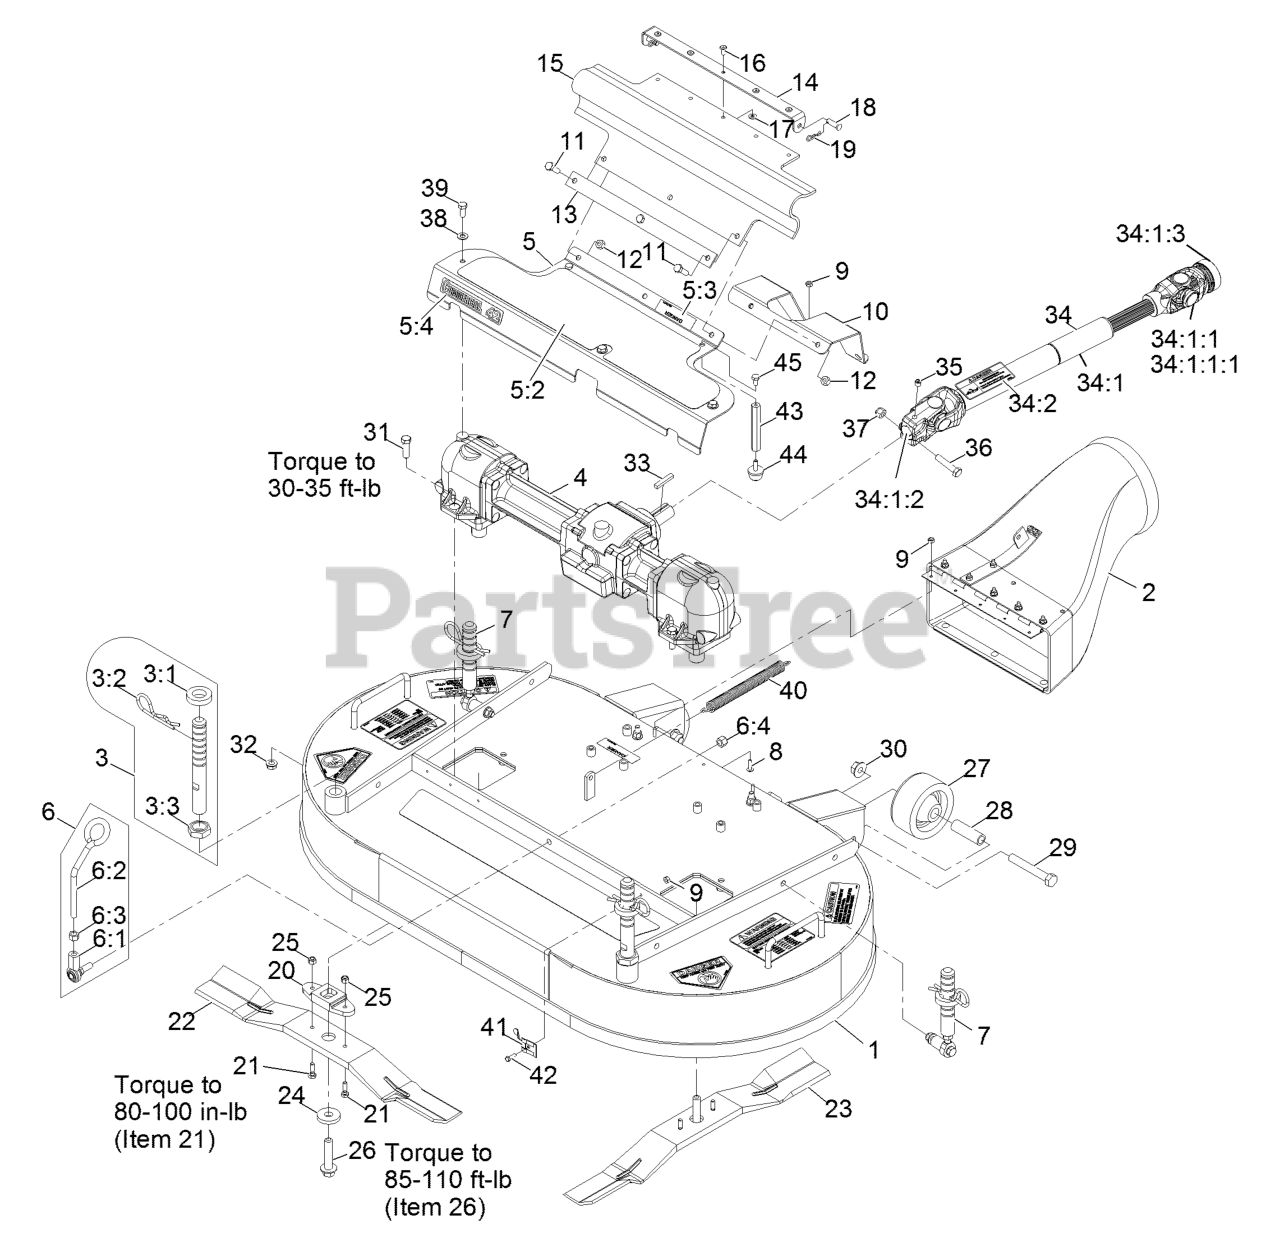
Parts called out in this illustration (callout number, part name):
1	DECK ASM
2	DISCHARGE TUBE ASM
3	FRONT DECK HEIGHT ADJUST
3:1	SPACER-DECK SUPPORT
3:2	PIN-CUT HEIGHT
3:3	NUT-JAM
4	GEARBOX ASM
5	ASM,GEARBOX COVER 42 W/DE
5:2	PAD-ANTI SKID
5:3	DECAL-COVER, MISSING
5:4	DECAL,COMMERCIAL 42
6	DECK LATCH ASM
6:1	BALLJOINT-RH
6:2	LATCH-DECK
6:3	NUT-HEX
6:4	NUT-LOCK
7	REAR DECK HEIGHT ADJUST A
8	SCREW-HEAD, TRUSS
9	NUT-LOCK, NI
10	GUARD-DRIVE SHAFT
11	SCREW-HH
12	NUT-LOCK, NI
13	STRAP-DRIVE, LINE COVER
14	BRACKET-GUARD, PTO
15	GUARD-PTO
16	RIVET-BLIND
17	WASHER-FLAT
18	PIN-CLEVIS
19	PIN-COTTER
20	DRIVER-BLADE
21	BOLT-SHEAR
22	BLADE,22 INCH RH
23	BLADE,22 INCH LH
25	NUT-LOCK, NI
26	BOLT-BLADE
27	ROLLER-DECK
28	SPACER-ROLLER
29	SCREW-HH
30	NUT-HHF
31	SCREW-HH
32	NUT-HHF, WHIZ
33	KEY-SQUARE
34	DRIVE SHAFT ASM
34:1	Shaft,Drive Telescoping
34:1:1	U-JOINT KIT
34:1:1:1	FITTING-GREASE
34:1:2	YOKE-KEYED
34:1:3	YOKE-QUICK DISCONNECT
34:2	DECAL-DRIVELINE
35	SCREW-SET, HSH
36	SCREW-HH
37	NUT-LOCK, NI
38	WASHER-PLAIN
39	SCREW-HH
40	SPRING-EXTENSION
41	CLIP-DECK, HOLD UP ROD
43	STAND-OFF
45	SCREW-HH
